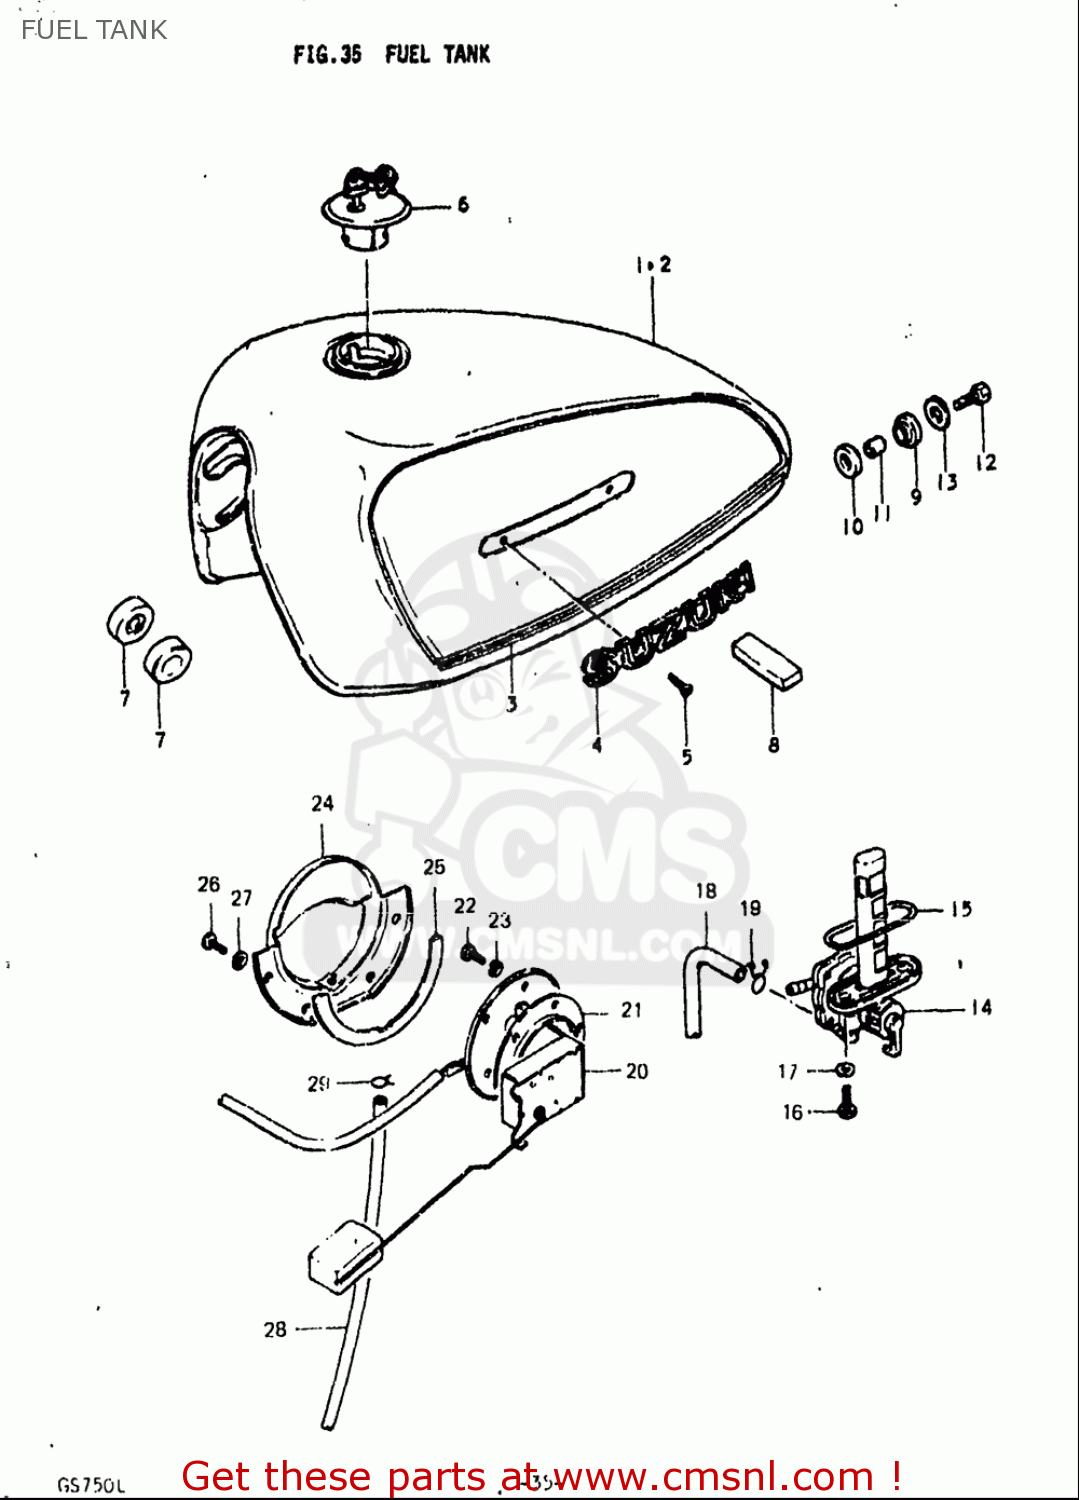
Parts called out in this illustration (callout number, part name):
4	EMBLEM,FUEL TANK
5	SCREW
6	CAP SET,FUEL TANK
7	CUSHION
8	CUSHION
9	CUSHION
10	CUSHION
11	SPACER(8.2X12X17)
12	BOLT
13	WASHER(8.5X28X1.6)
15	O RING
16	BOLT(6X20)
17	GASKET(5.8X13X1.2) (NAS)
18	HOSE(7X10.2X2000)
19	CLIP
21	GASKET,FUEL LEVEL GAUGE (NAS)
22	BOLT
23	WASHER,LOCK
25	GASKET,FUEL DRAIN PLATE (NAS)
26	SCREW
27	WASHER,LOCK
28	HOSE(5X8.2X2000)
29	CLIP
